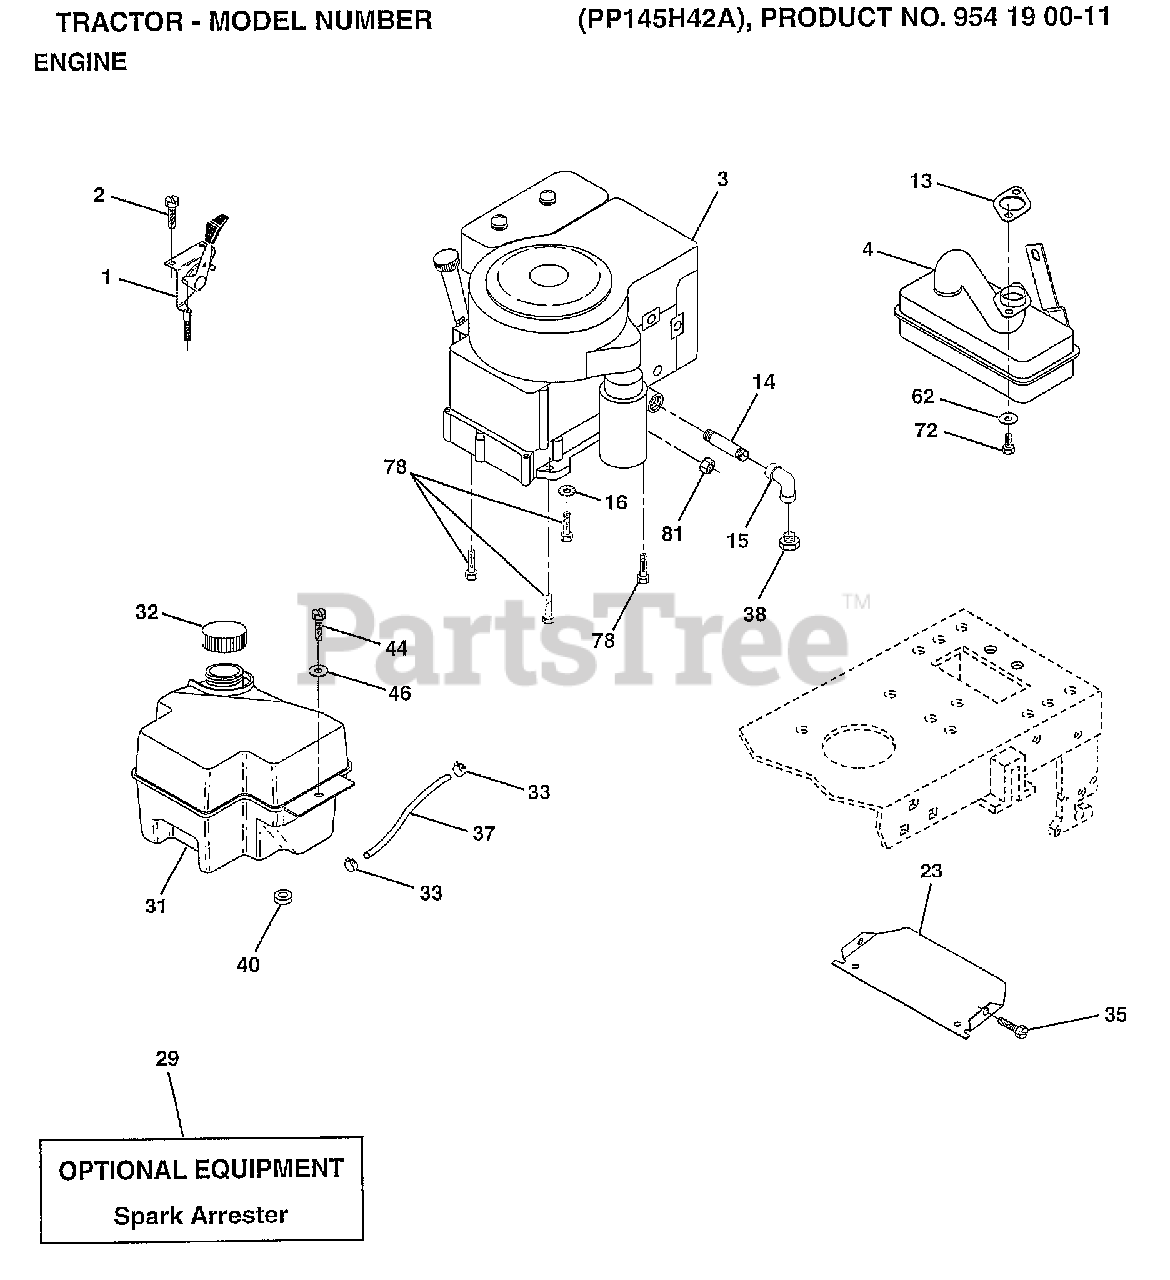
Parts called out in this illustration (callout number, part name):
1	CONTROL.THTL.23.5
2	SCREW LT
4	MUFFLER
13	GASKET MUFFLE TEC
14	PIPE NIPPLE LT
15	ELBOW
16	LOCKWASHER
23	SHIELD-HEAT
32	CAP ASM FUEL
33	HOSE CLAMP
35	SCREW
37	LINE FUEL
44	SCREW HEX CRT
46	WASHER
49	SCREW GTV
62	LOCKWASHER
72	SCREW HEX HD CAP
78	SCREW
81	NUT
